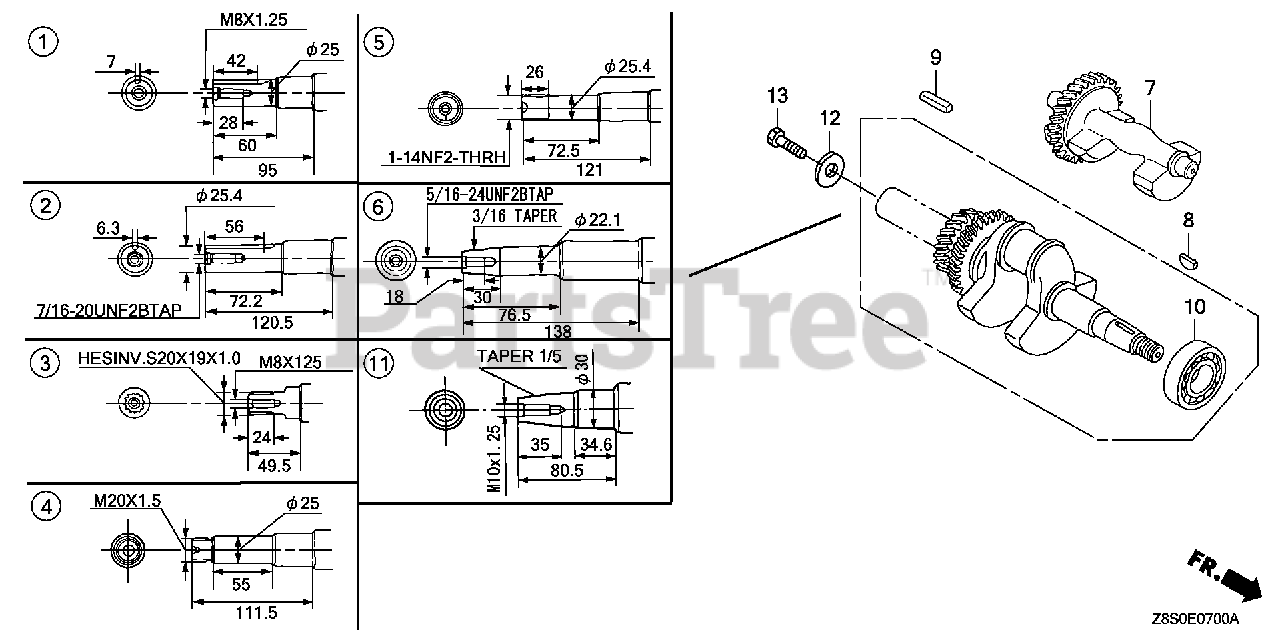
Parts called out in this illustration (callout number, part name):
2	CRANKSHAFT
7	WEIGHT, BALANCER
8	KEY, SPECIAL WOODRUFF (25X18)
9	KEY (6.3X6.3X43)
10	BEARING, RADIAL BALL (6206 SH)
